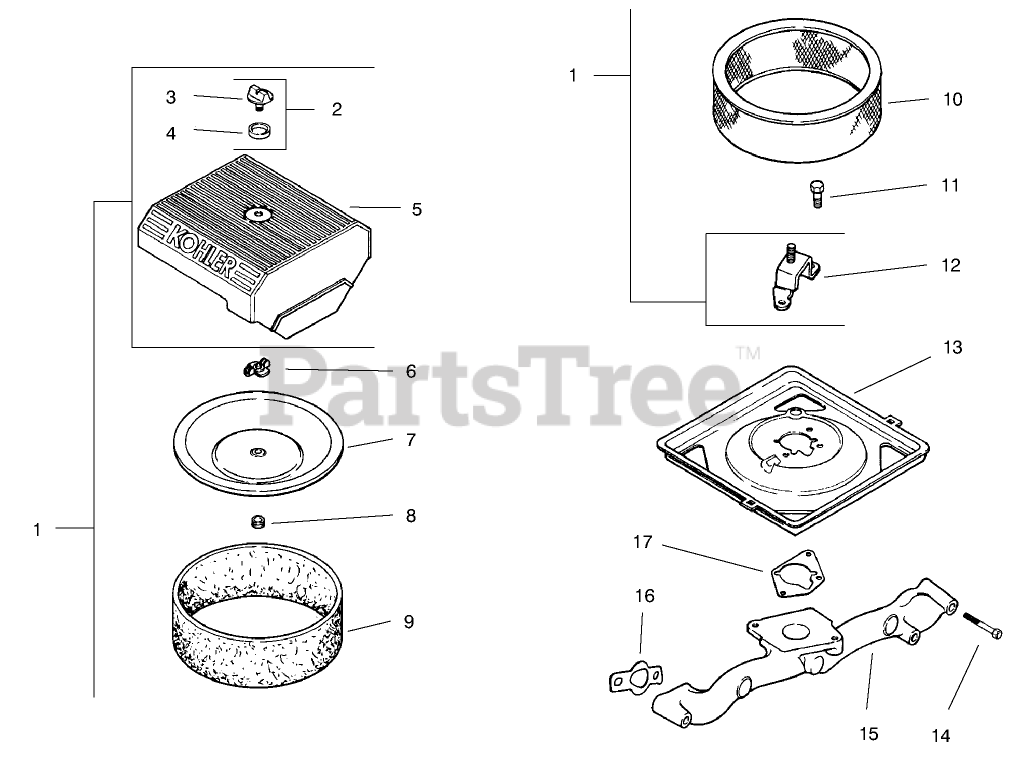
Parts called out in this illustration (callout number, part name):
1	Kit, air cleaner cover (Incl. 2-5, 12)
2	Kit, knob with seal (Incl. 3-4)
3	Knob-Cover
4	O-Ring
5	Cover-Air Cleaner
6	Wingnut
7	Cover-Inner AirCleaner
8	Seal, insert
9	Bement-Precleaner
10	Bement-Air Cleaner
11	Screw
12	Bracket-Air Cleaner
13	Base-Air Cleaner
14	Screw
15	Manifold
16	Gasket-Intake, Manifold
17	Gasket
